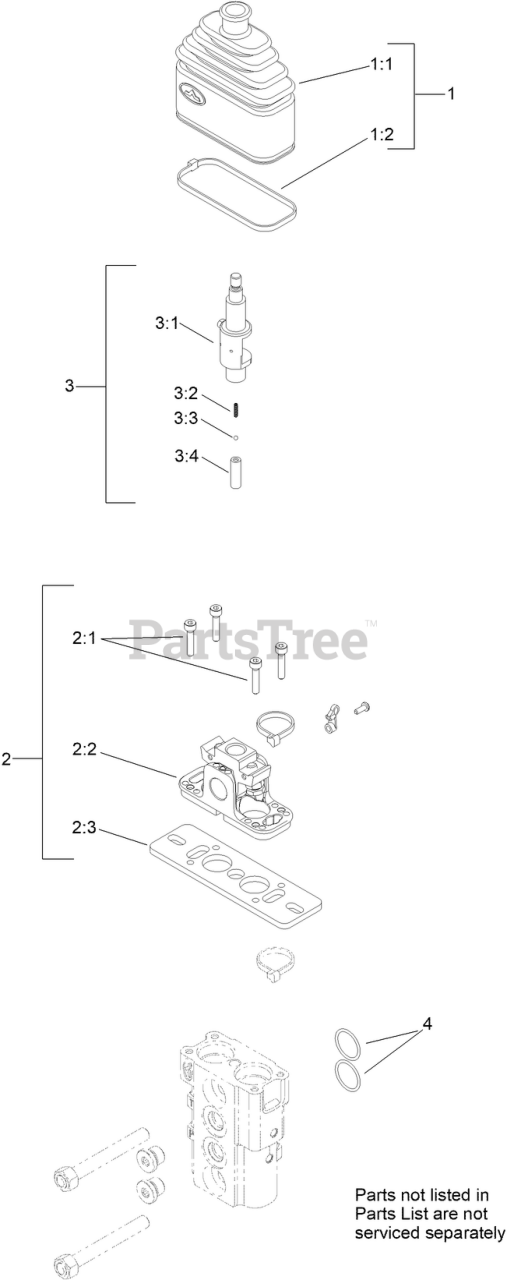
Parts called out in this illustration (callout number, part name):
1	BELLOW KIT
1:1	BELLOW-RUBBER
1:2	TIE-CABLE
2	FULCRUM KIT
2:1	Screw
2:2	SUPPORT KIT
2:3	PLATE-MOUNTING
3	SWITCH HOLDER LEVER KIT
3:1	LEVER-HOLDER, SWITCH
3:2	SPRING-RETURN
3:3	SPHERE
3:4	HOLDER-SPRING
4	O-RING
